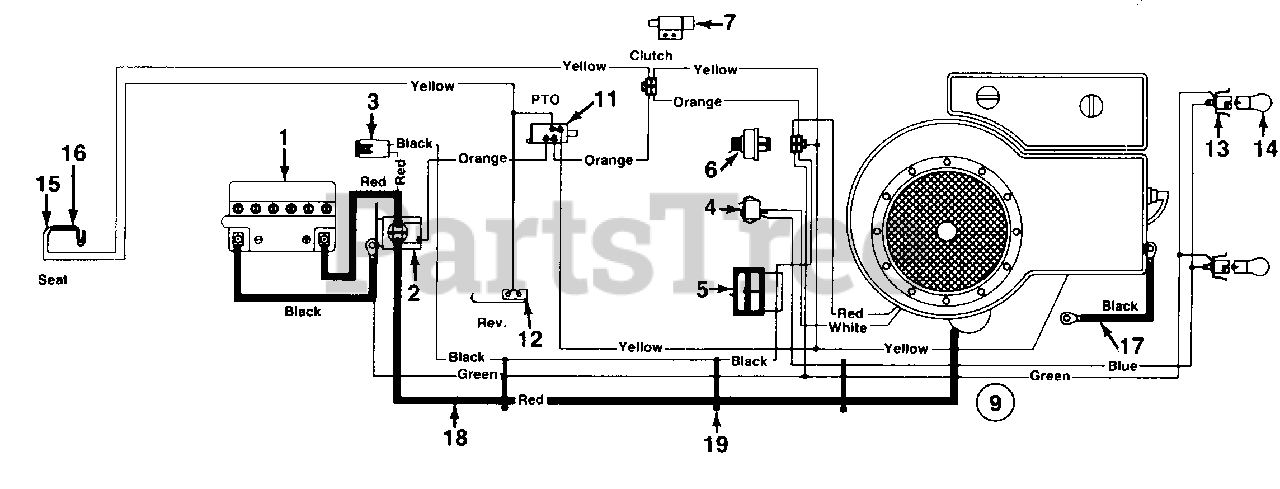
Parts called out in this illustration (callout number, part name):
1	Battery
2	Solenoid
3	Fuse 7.5 Amp.
4	Light Switch
5	Ammeter
6	Ignition Switch
7	Safety Switch
9	Wire Harness
11	Safety Switch
12	Safety Switch
13	Socket
14	Bulb
15	Safety-Switch
16	Safety Switch
17	Ground Wire 7.5" Lg.
18	Electric Wire
19	Cable Tie
